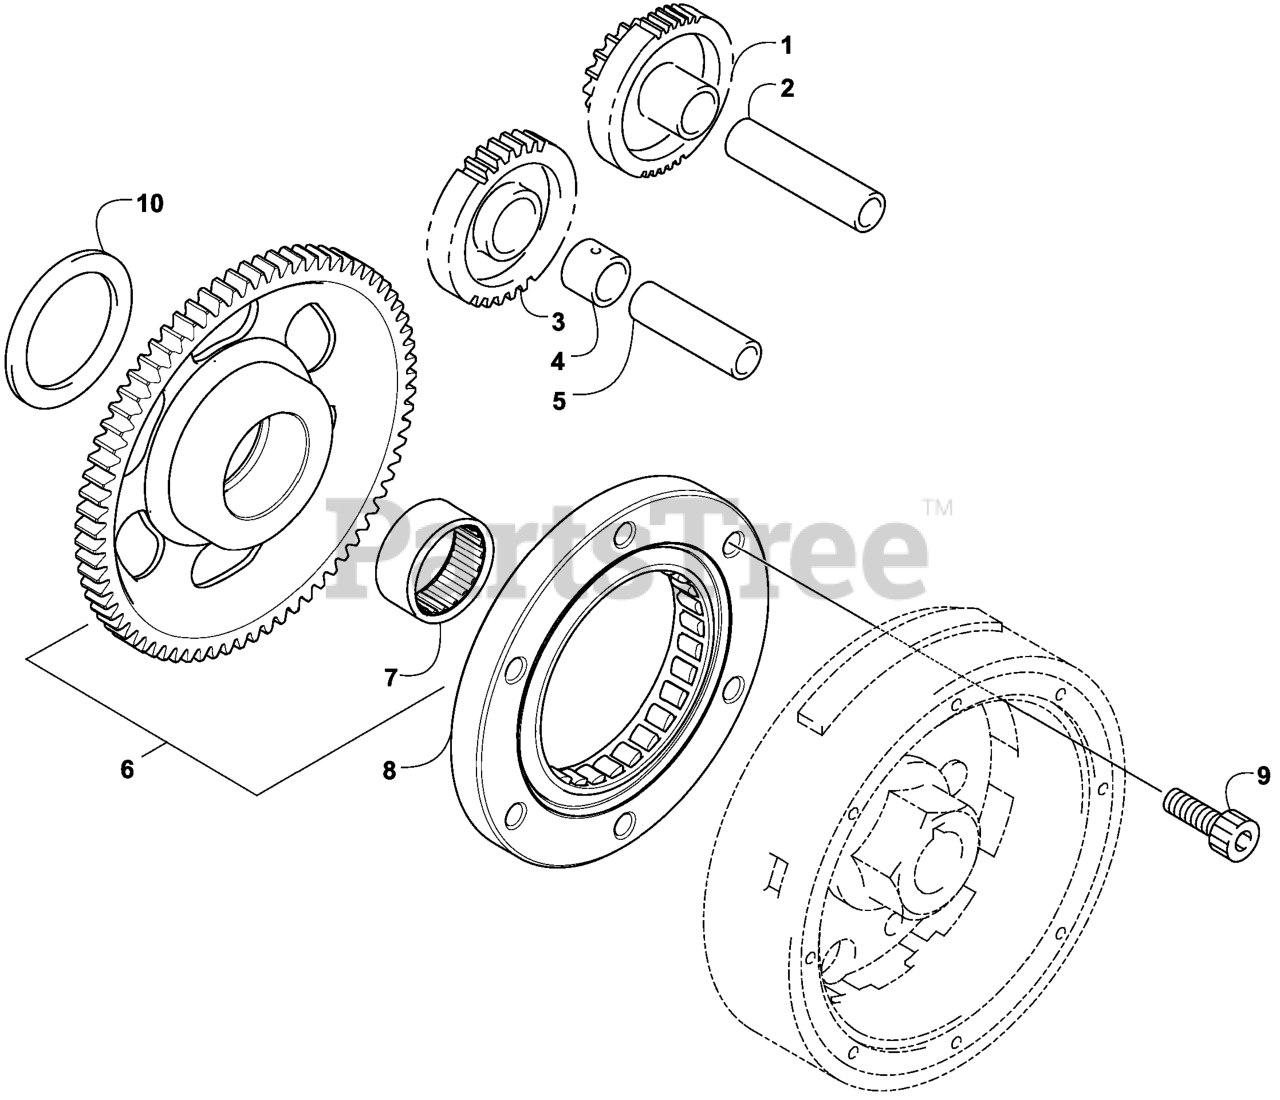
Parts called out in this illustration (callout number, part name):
1	GEAR-STARTER IDLER, 44T/1
2	SHAFT-STARTER GEAR
3	GEAR-STARTER IDLER, 27T (
4	SPACER-STARTER IDLER, GEA
5	SHAFT-STARTER GEAR
6	GEAR-STARTER CLUTCH, 73T
7	BEARING-NEEDLE, ROLLER
8	CLUTCH-ONE WAY (W/ HUB AS
9	SCREW-TORX SOCKET HEAD
10	WASHER-STEEL
